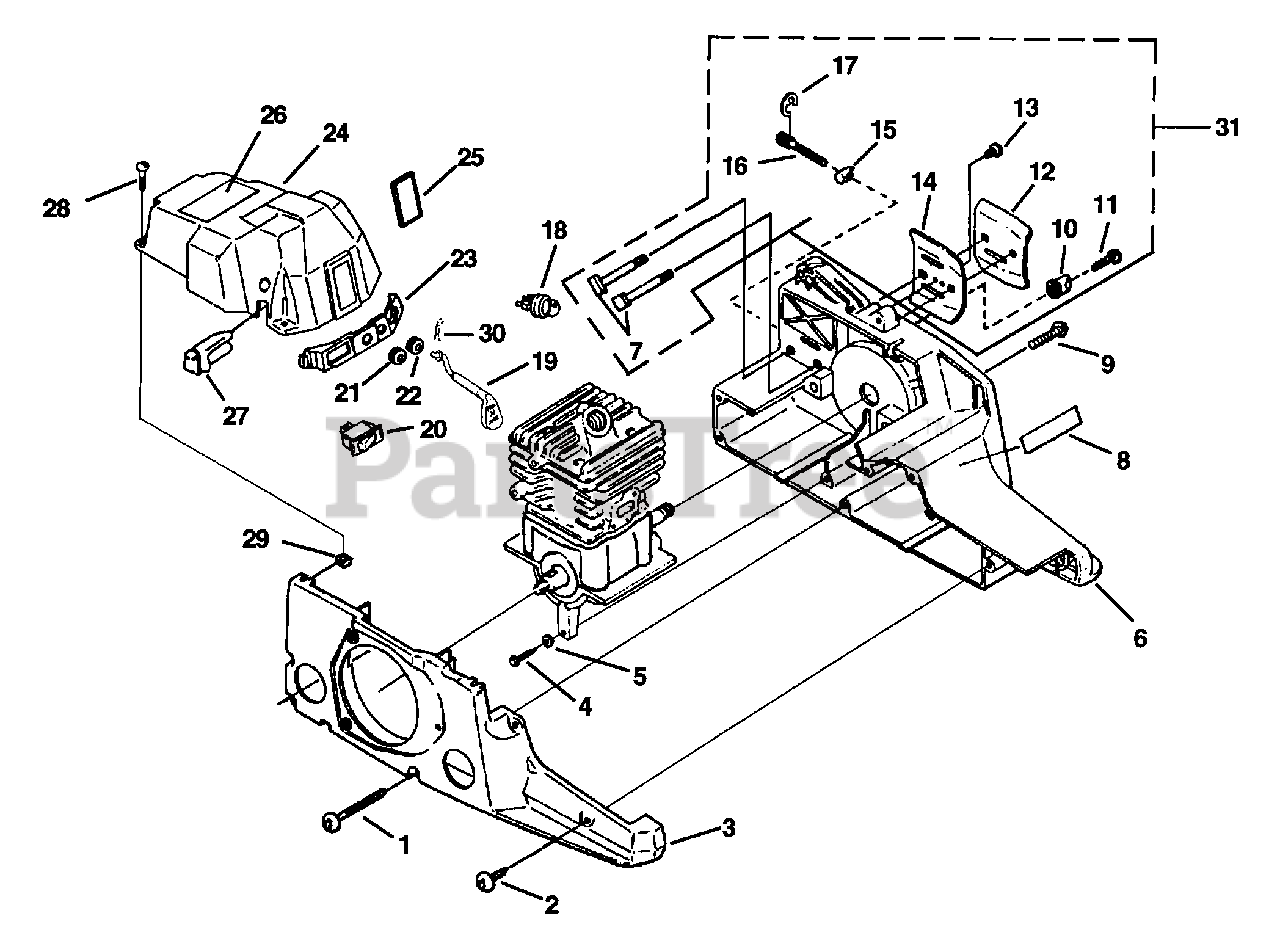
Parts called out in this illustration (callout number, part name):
1	SCREW-Thread Form (8-16 x 1 3/4")
2	SCREW-Thread Form. (8-16 x 5/8")
3	HOUSING-Starter Side
4	SCREW-Thread Form. (10-14 x 1 1/8")
5	WASHER-Lock
6	HOUSING-Drive Side
7	BOLT-Guide Bar
8	DECAL-Panel
9	SCREW-Hex Hd. (12-24 x 1")
10	STOP-Chain
11	SCREW-Thread Form (10-14 x 7/8")
12	PLATE-Guide Bar (Outer)
13	SCREW-Thread Form. (6-19 x 1/2")
14	PLATE-Guide Bar (Inner)
15	PIN-Adjusting
16	SCREW-Guide Bar Adjusting
17	RING-Snap
18	BULB-Primer
19	ROD-Choke
20	SWITCH-Ign.
21	BOOT-Throttle Cable
22	GROMMET-Choke
23	PANEL-Control
24	CYLINDER COVER
25	SCREEN-Air Inlet
26	LABEL-Warning
27	GROMMET-Carburetor
28	SCREW-Round Hd. (10-24 x .710)
29	NUT-Square (10-24)
30	PIN-Cotter
31	GUIDE BAR FASTENER KIT
